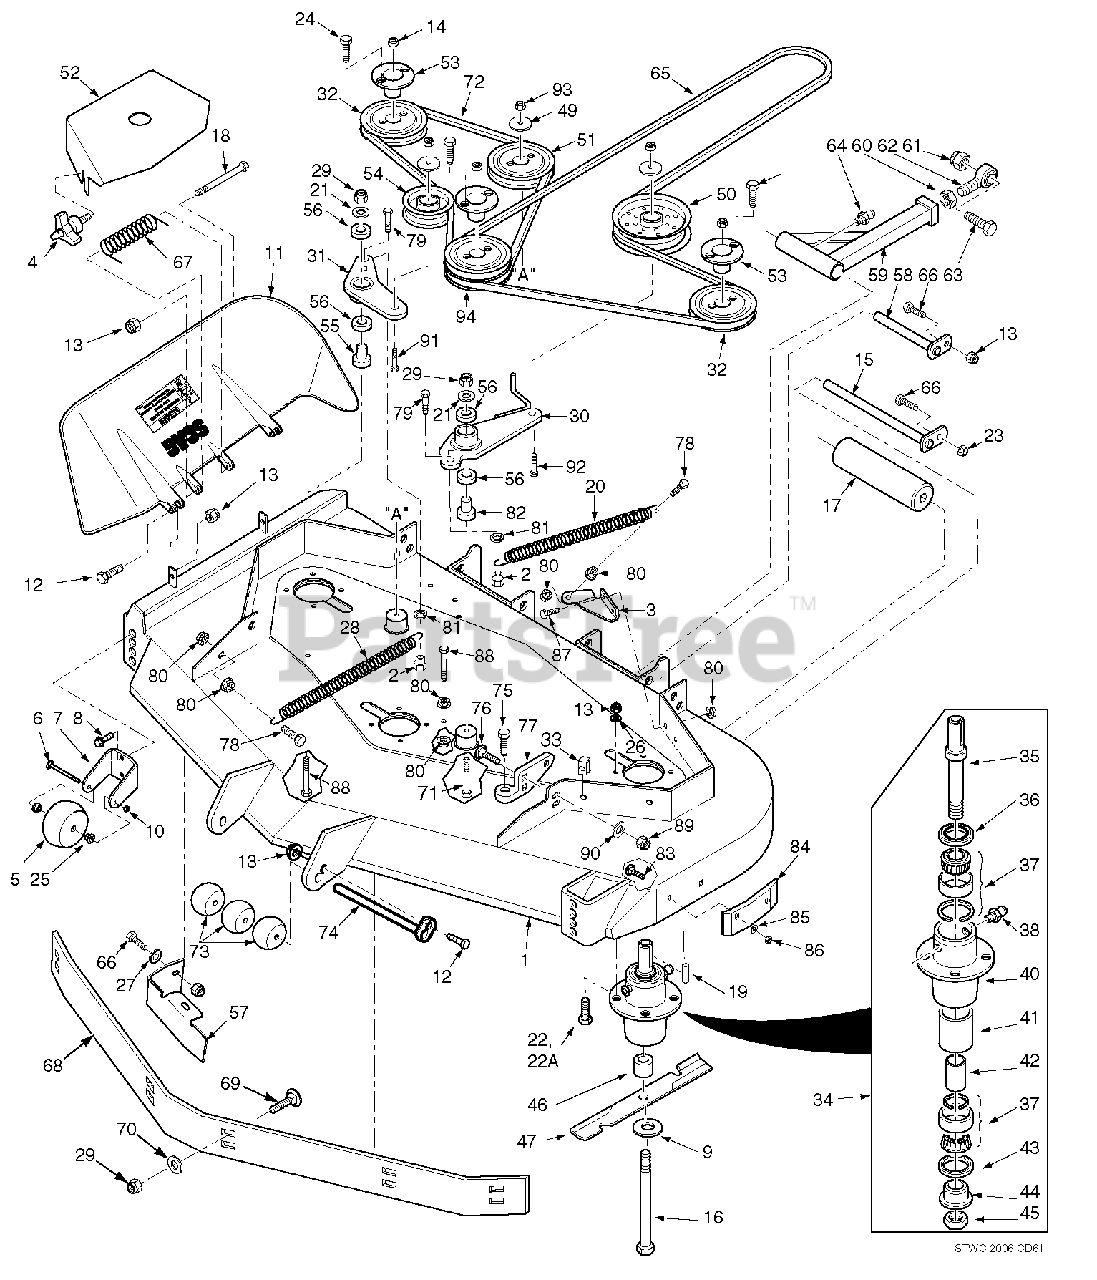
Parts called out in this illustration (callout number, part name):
1	Cutter Deck Velocity Plus
2	Boss, Spring Anchor
3	Bracket, LH Spring Anchor
4	Wing Nut, 3/8-16
5	Anti-Scalp Wheel
6	Bolt, Carriage 3/8-16 x 4"
7	Bracket, Anti-Scalp Wheel
8	Bolt, Serrated Flange 3/8-16 x 1"
9	Flatwasher, 5/8" Hardened
10	Locknut, 3/8-16 Center Lock
11	Discharge Chute
12	Bolt, Hex Head 5/16-18 x 1-1/2", Rear
13	Nut, Elastic Stop 5/16-18
14	Nut, 5/8-11 UNC
15	Shaft, Roller
16	Bolt, Hex Head 5/8-11 x 9-1/2"
17	Roller, Rear
18	Bolt, Hex Head 5/16-18 x 4-3/4"
19	Key, 1/4 x 1/4 x 2"
20	Spring, LH Deck Drive
21	Flatwasher, 3/8" - .938 x .391 x .105"
22	Bolt, Hex Head 5/16-18 x 1-3/4" Grade 8
23	Nut, Serrated Flange 5/16-18
24	Bolt, Hex Head 1/4-20 x 1" Grade 8
25	Bushing, .376 ID Oilite
26	Lockwasher 5/16"
27	Flatwasher 5/16"
28	Spring, RH Deck Drive
29	Nut, Elastic Stop 3/8-16
30	Idler Arm Assembly, LH Drive
31	lder Arm Assembly, RH Drive
32	Pulley, Tapered Bore 6.33" Dia.
33	U-Nut, 3/8-16
34	Spindle Assembly
35	Shaft, Spindle
36	Seal Upper
37	Bearing Assembly
38	Grease Fitting
39	Valve, Grease Relief
40	Housing, Spindle
41	Spacer, Outside
42	Spacer, Inside
43	Seal, Lower
44	Bushing, Bottom
45	Nut, Special 1-1/16 - 18
46	Spacer, Spindle
47	Cutter Blade 21"
48	Pulley, Double Groove 6.33" Dia.
49	Dust Shield
50	Idler Pulley, 5" Dia.
51	Idler Pulley, 5" Dia.
52	Belt Cover
53	Hub, Tapered 1-1/8" Bore
54	Idler Pulley, 3-1/2" Dia.
55	Pivot, Idler
56	Bearing
57	Turbo Baffle, Bolt On
58	Push Arm Shaft
59	Push Arm
60	Nut, 5/8-18 UNF
61	Nut, Elastic Stop 5/8-11
62	Rod End, 5/8 Male RH Thread
63	Bolt, Hex Head 5/8-11 x 4-1/2"
64	Grease Fitting, 90 Degree
65	Belt, Deck Drive 61V
66	Bolt, Hex Head 5/16-18 x 1"
67	Spring, Discharge Chute
68	Baffle Custom-Cut,
69	Bolt, Carriage 3/8-16 x 1"
70	Flatwasher, 3/8-.391 x .938 x .105"
71	Bolt, Hex Head 3/8-16 X 3-1/2"
72	Belt, Deck Drive RH
73	Wheel, Anti Scalp
74	Roller Shaft
75	Bolt, Special
76	Bolt, Carriage 7/16-14 x 1-1/4"
77	Lever Assy., Deck Level
78	Bolt, Hex Head 3/8-16 x 1-1/2" Gr.8
79	Bolt, Hex Head 3/8-16 x 1"
80	Nut, Serrated Flange 3/8-16
81	Lockwasher, 5/16"
82	Pivot, Idler Short
83	Bolt, Carr. 5/16-18 x 3/4"
84	Wear Pad
85	Flatwasher, 5/16-.344 x .688 x .065"
86	Nut, Center Lock 5/16"
87	Bolt, Hex Head 3/8-16 x 1"
88	Bolt, Hex Head 3/8-16 x 2-1/2"
89	Nut, Elastic Stop 7/16-14
90	Flatwasher, 7/16-.500 x 1.250 x .083"
91	Bolt, Hex Head 3/8-16 x 2-1/4"
92	Bolt, Hex Head 3/8-16 x 3"
93	Nut, Elastic Stop 3/8-16
94	Pulley, Double Groove 6.33" Dia.
